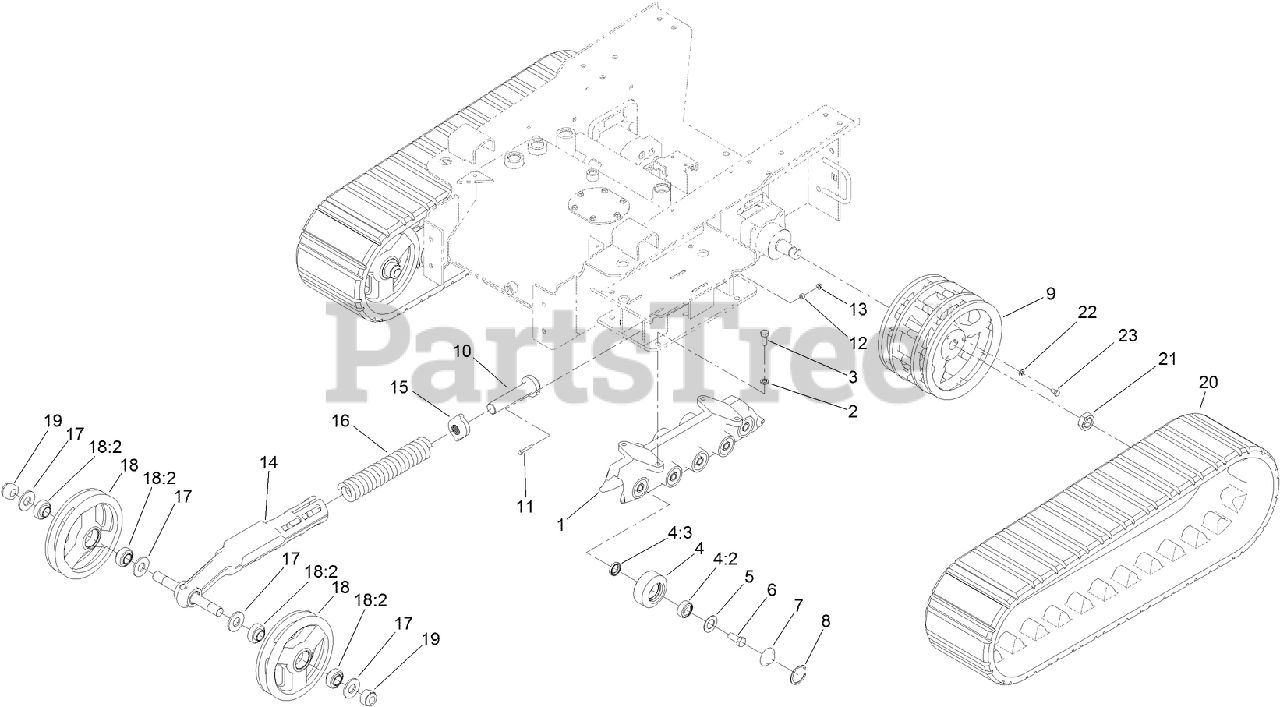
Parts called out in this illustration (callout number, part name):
1	GUIDE-TRACK, TX WIDE
2	WASHER-LOCK
3	SCREW-HH
4	ROAD WHEEL ASM
4:2	BEARING-BALL
4:3	SEAL-OIL
5	GASKET-BOGIE
6	SCREW-HH
7	CAP-WHEEL, BEARING
8	RING-SNAP, INTERNAL
9	WHEEL-DRIVE
10	BOLT-TENSIONER
11	SCREW-HH
12	SPACER
13	NUT-HHF
14	ARM-TENSIONER
15	BLOCK-TENSIONER
16	SPRING-COMPRESSION
17	WASHER-PLAIN
18	TENSIONER WHEEL ASM
18:2	BEARING-BALL
19	NUT-HEX, NI
21	NUT-HEX
22	WASHER-LOCK
23	SCREW-HH
